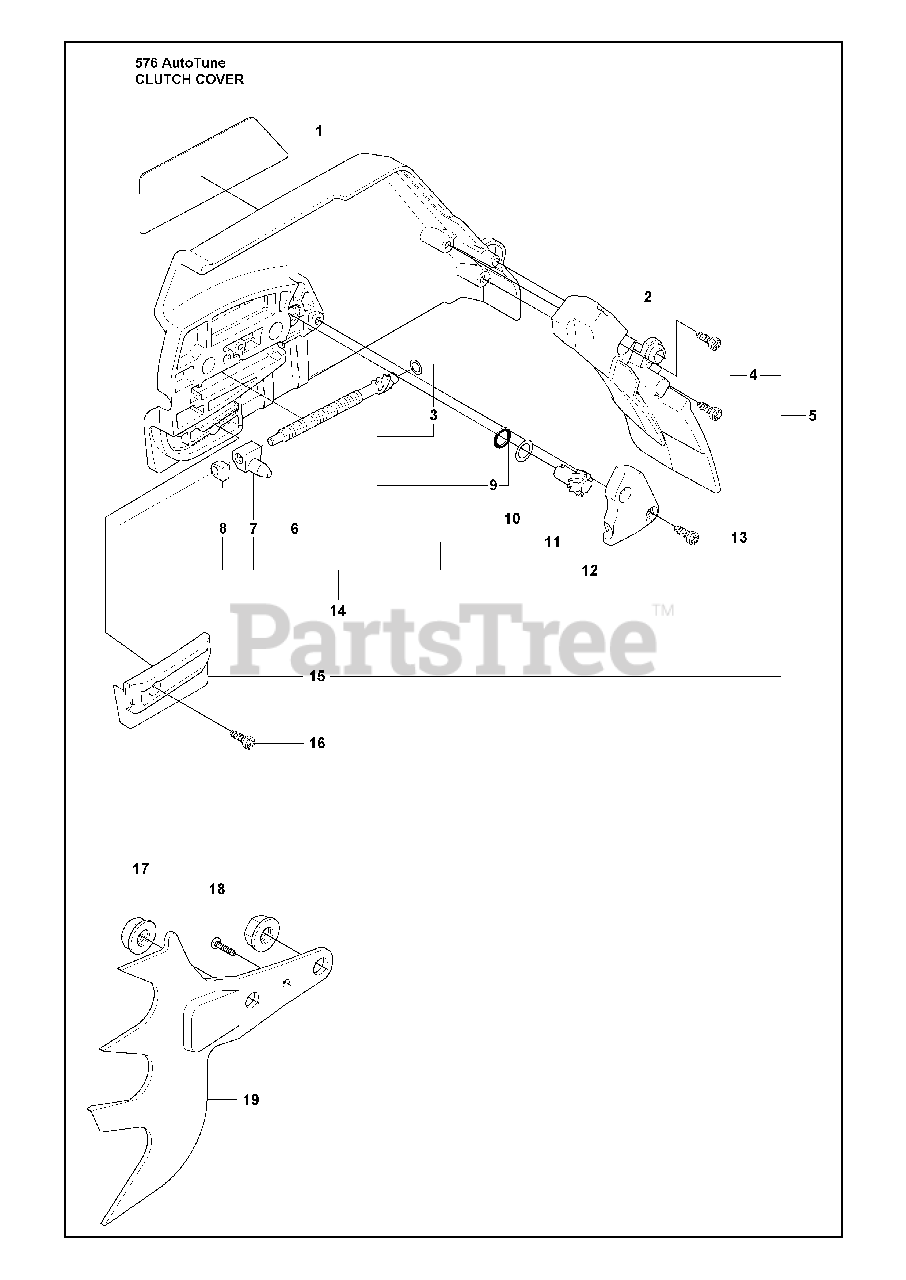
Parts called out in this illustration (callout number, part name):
5	CLUTCH COVER ASSY
6	WORM SCREW / ADJUSTER
11	RP ADJUSTER
14	KIT-CHAIN TENSIONER
15	CHAIN GUIDE
17	NUT M8 FLANGE
19	FELLING DOG
